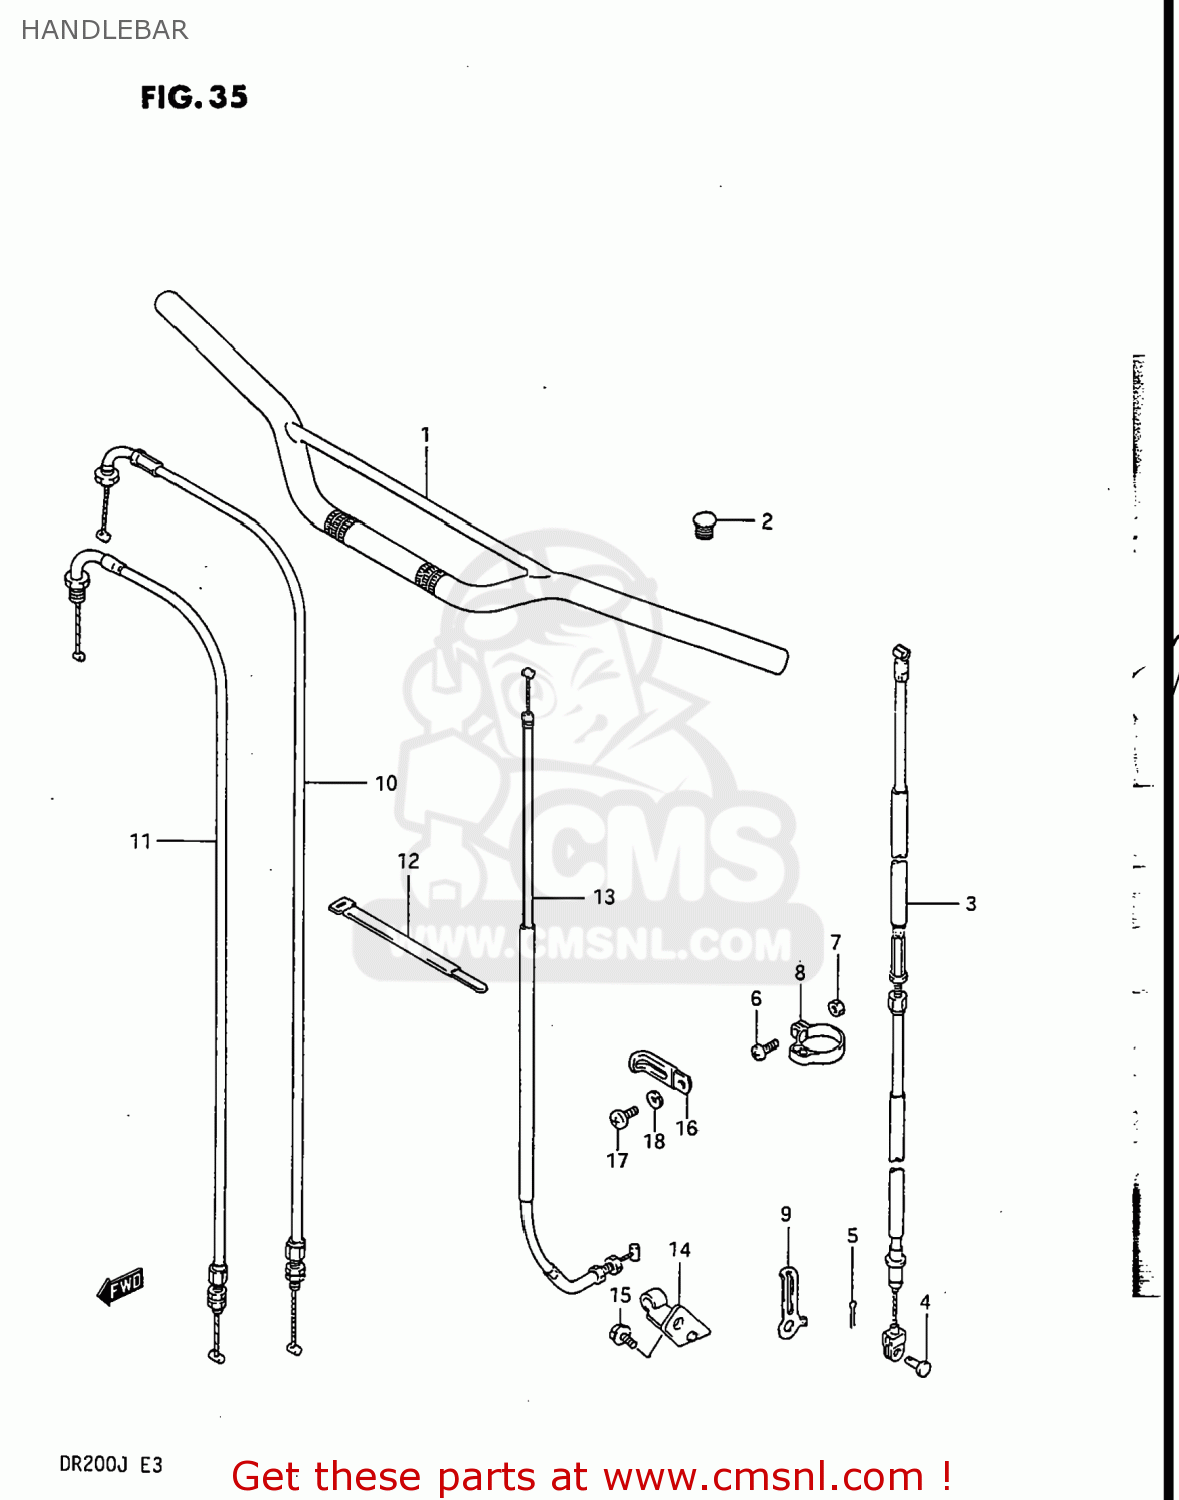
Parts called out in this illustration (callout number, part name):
1	HANDLEBAR
2	CAP(OD:14)
3	CABLE ASSY,CLUTCH
4	PIN(L:15)
5	PIN
6	SCREW
7	NUT 5MM
8	CLAMP,CABLE
9	CLAMP,CABLE
10	CABLE ASSEMBLY,THROTTLE
11	CABLE ASSEMBLY,THROTTLE
12	CLAMP
13	CABLE ASSY,DECOMP
14	BRACKET,DECOMP CABLE
15	BOLT 6X12
16	CLAMP
17	SCREW 6X12
18	WASHER,LOCK
